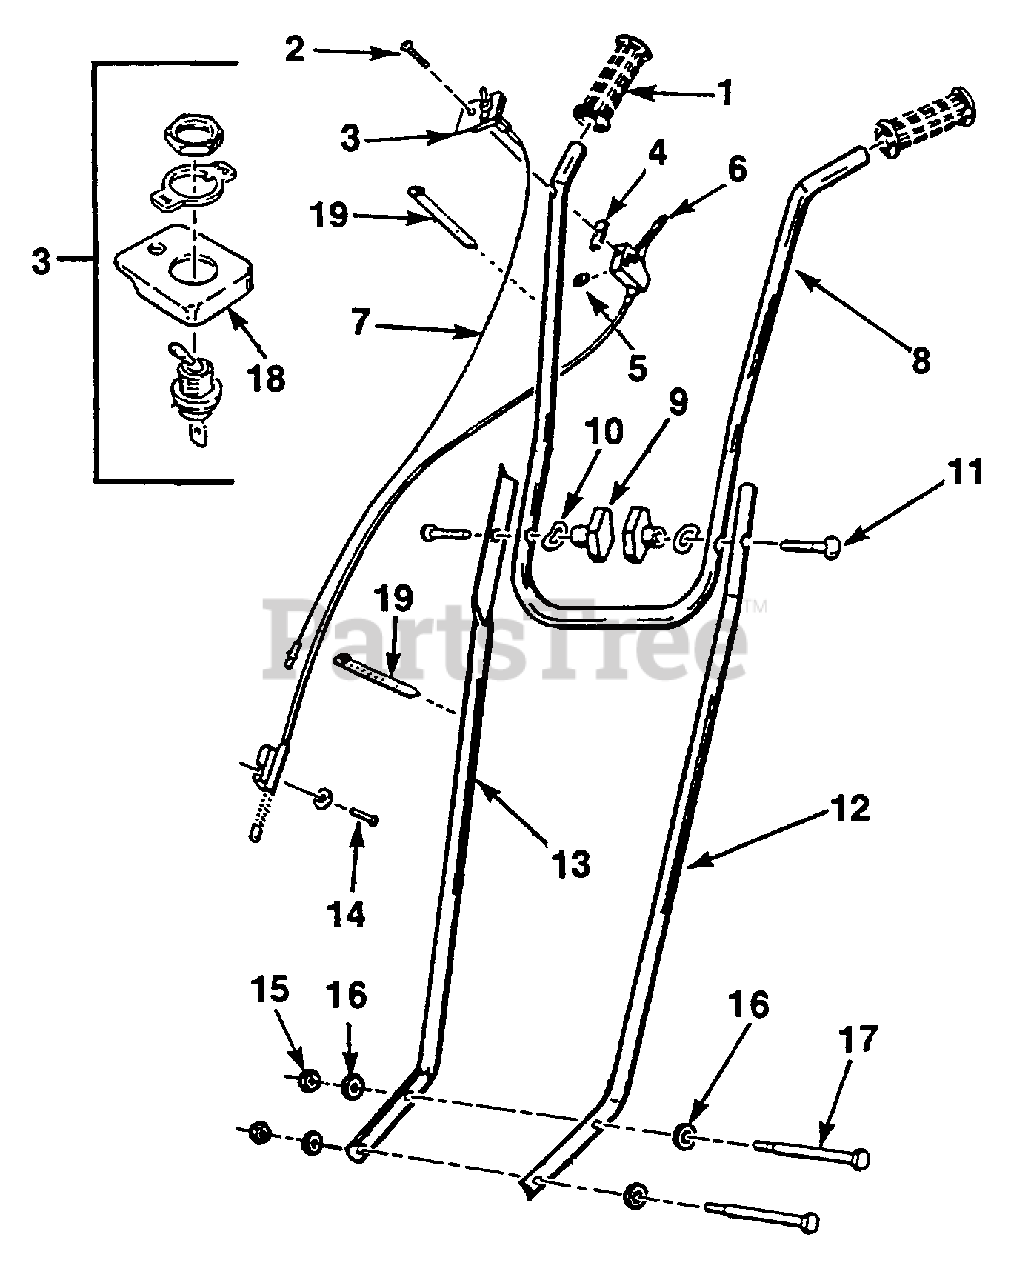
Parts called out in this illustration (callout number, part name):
1	GRIP- Handlebar
2	SCREW- Set, #10-24 x 1 3/8"
3	SWITCH ASSY.- w/Mounting Plate
4	ISOLATOR
5	NUT- Throttle/Switch Assy.
6	THROTTLE CABLE ASSY. w/Throttle Trigger
7	WIRE ASSY.- Ground
8	HANDLEBAR- Upper
9	KNOB- Plastic Handlebar 5/16"
10	WASHER- Curved Knob 5/16"
11	SCREW- Curved Head 5/16-18 x 1 1/2"
12	HANDLEBAR- Lower L.H.
13	HANDLEBAR- Lower R.H.
14	SCREW- #8-32 x 1.0 hex hd.
15	NUT- Flex-Loc 1/4-20
16	WASHER- Curved 5/16"
17	SCREW- 1/4-20 x 4 1/2"
18	MOUNTING PLATE
19	TIE STRAP
